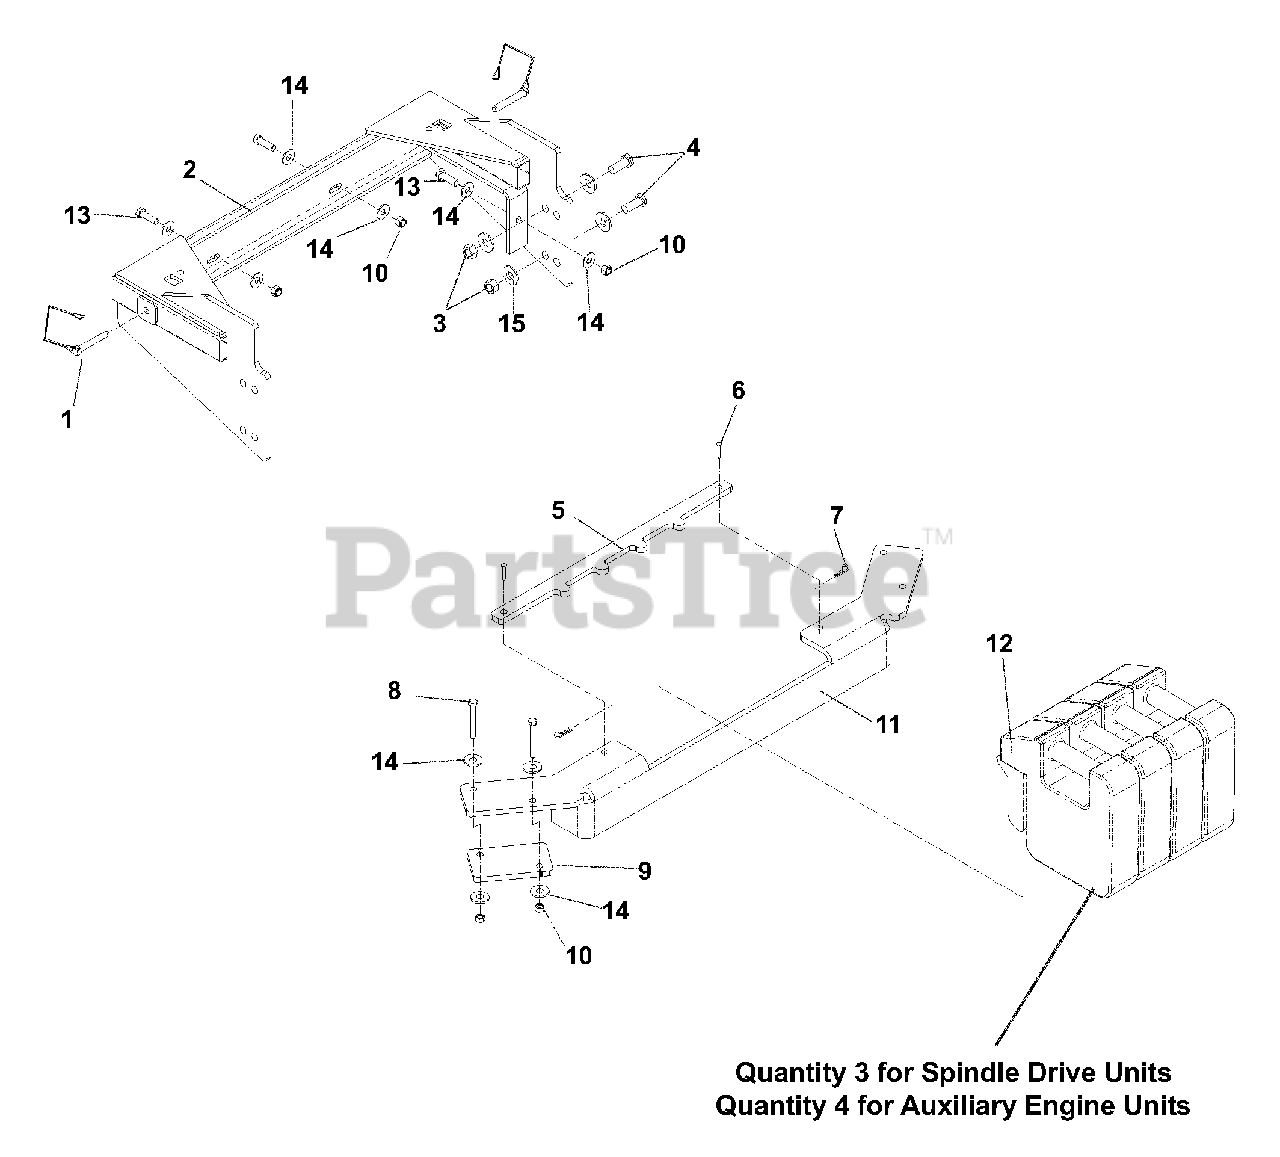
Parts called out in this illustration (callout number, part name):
1	PIN, WIRE LOCK
2	HITCH, GEN II
2	HITCH, GEN I
3	NUT 1/2 NYLOC
4	BOLT, 1/2-13 X 1 1/2
5	FRONT WEIGHT HOLD BAR
6	CLEVIS PIN, 3/8 X 1
7	HAIR PIN, #11
8	BOLT, 3/8-16 X 3 1/2
9	FRONT WEIGHT CLAMP
10	NUT, 3/8-16, NYLOC
11	FRONT WEIGHT BAR
12	FRONT WEIGHT
13	BOLT, 3/8-16 X 1 1/4
14	WASHER, 3/8
15	WASHER, 1/2
